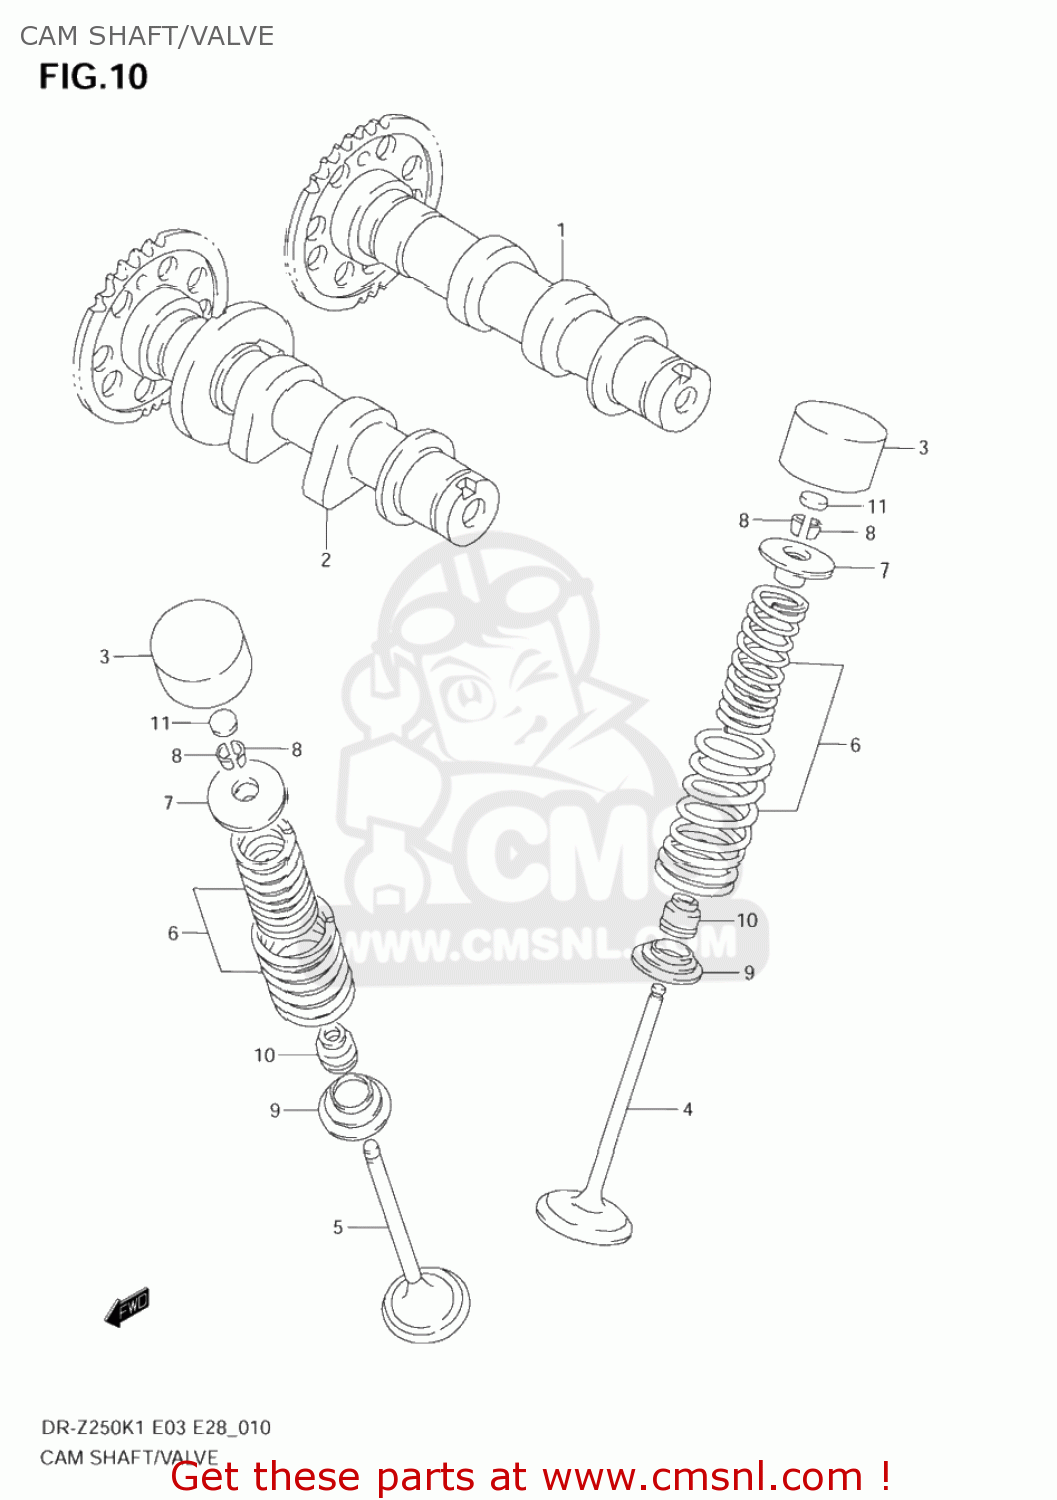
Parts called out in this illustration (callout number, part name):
1	CAMSHAFT,INTAKE
2	CAMSHAFT,EXHAUST
3	TAPPET
4	VALVE,INTAKE
5	VALVE,EXHAUST
6	SPRING SET,VALVE
7	RETAINER,VALVE SPRING
8	COTTER VALVE
9	SEAT,VALVE SPRING
10	SEAL,OIL(4.5X10X8)
11	SHIM,TAPPET
12	SHIM SET,TAPPET
13	CASE,TAPPET SHIM
